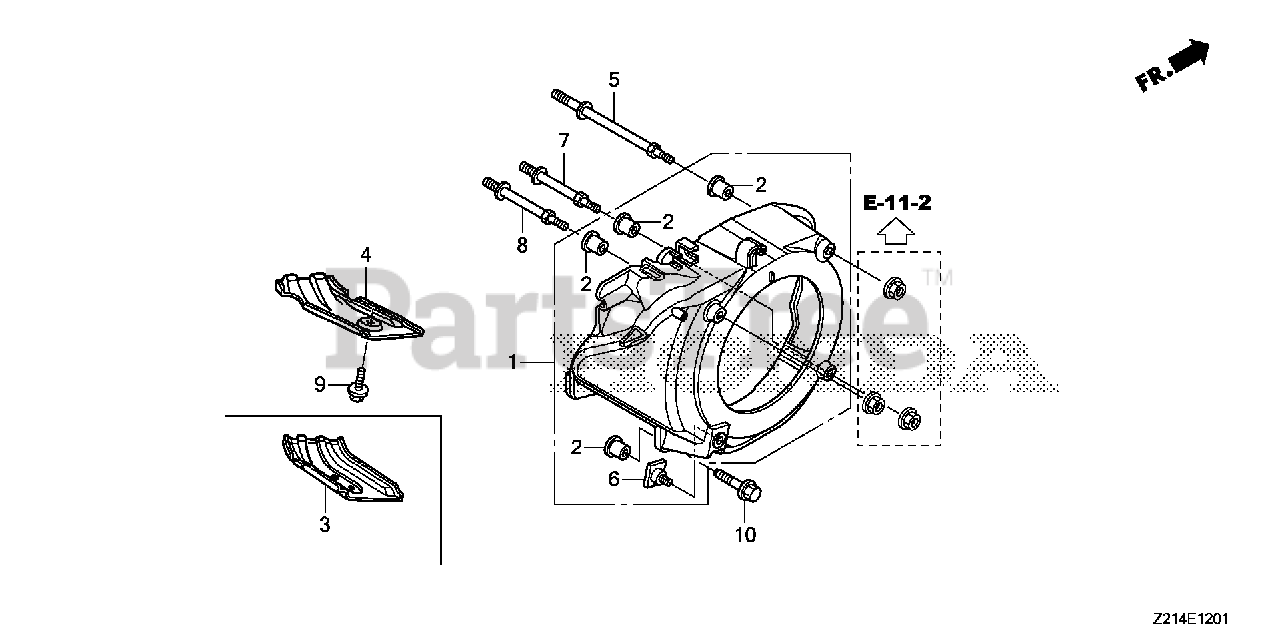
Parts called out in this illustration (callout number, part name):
1	COVER, FAN *NH1* (BLACK)
2	COLLAR, FAN COVER
5	BOLT, STUD (SEL)
6	BOLT, SPECIAL (6MM)
7	BOLT, STUD
8	BOLT B, STUD
9	BOLT, FLANGE (6X12) (CT200)
10	BOLT, FLANGE (6X25) (CT200)
